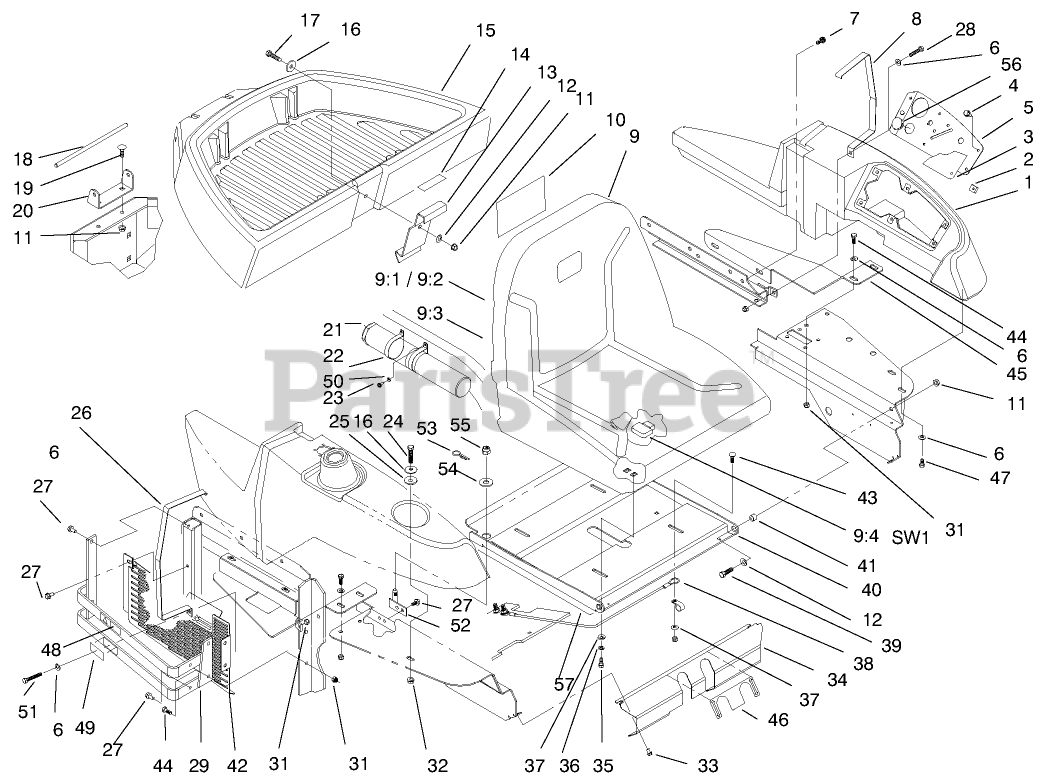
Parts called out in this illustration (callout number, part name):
1	CONSOLE
2	CLIP-TINNERMAN
3	DECAL - INSTRUMENT
4	SCREW-PPH
5	PANEL - INSTRUMENT
6	WASHER-PLAIN
7	SCREW-HWHTF
8	STRAP-CONSOLE
9	SEAT ASM
9:1	SHELL
9:2	SEAT CUSHION KIT
9:3	EDGING
9:4	SWITCH-SEAT
9:5	SCREW-HH
11	NUT-LOCK, NI
12	WASHER-FLAT
16	WASHER
21	TUBE-MANUAL
22	CLAMP-R
23	RIVET-BLIND
24	SCREW-HH
25	BUSHING-FLANGE
26	STRAP-TANK, FUEL
27	SCREW-HWHTF
28	SCREW-HH
29	BUMPER ASM
30	PLATE-SUPPORT, TANK
31	NUT-LOCK, NI
32	NUT-HHF, WHIZ
33	SCREW-HWH
34	PLATE - COVER, FRONT
35	SCREW-HH
36	WASHER-LOCK
37	WASHER-FLAT
38	CABLE-SEAT
39	SCREW-HH
40	SEAT PLATE ASM
41	SPACER-WHEEL
42	GUARD - BELT
43	BOLT-CARR
44	SCREW-HH
45	PLATE - CONSOLE SUPT R
46	DECAL-CONTROL, STEERING
47	SCREW-HH
48	DECAL-WARNING
49	DECAL-SURFACE, HOT
50	WASHER-FLAT
51	SCREW-HH
52	LATCH ASM
54	WASHER-FLAT
55	NUT-LOCK, NI
57	FOAM - PLATE, SEAT
